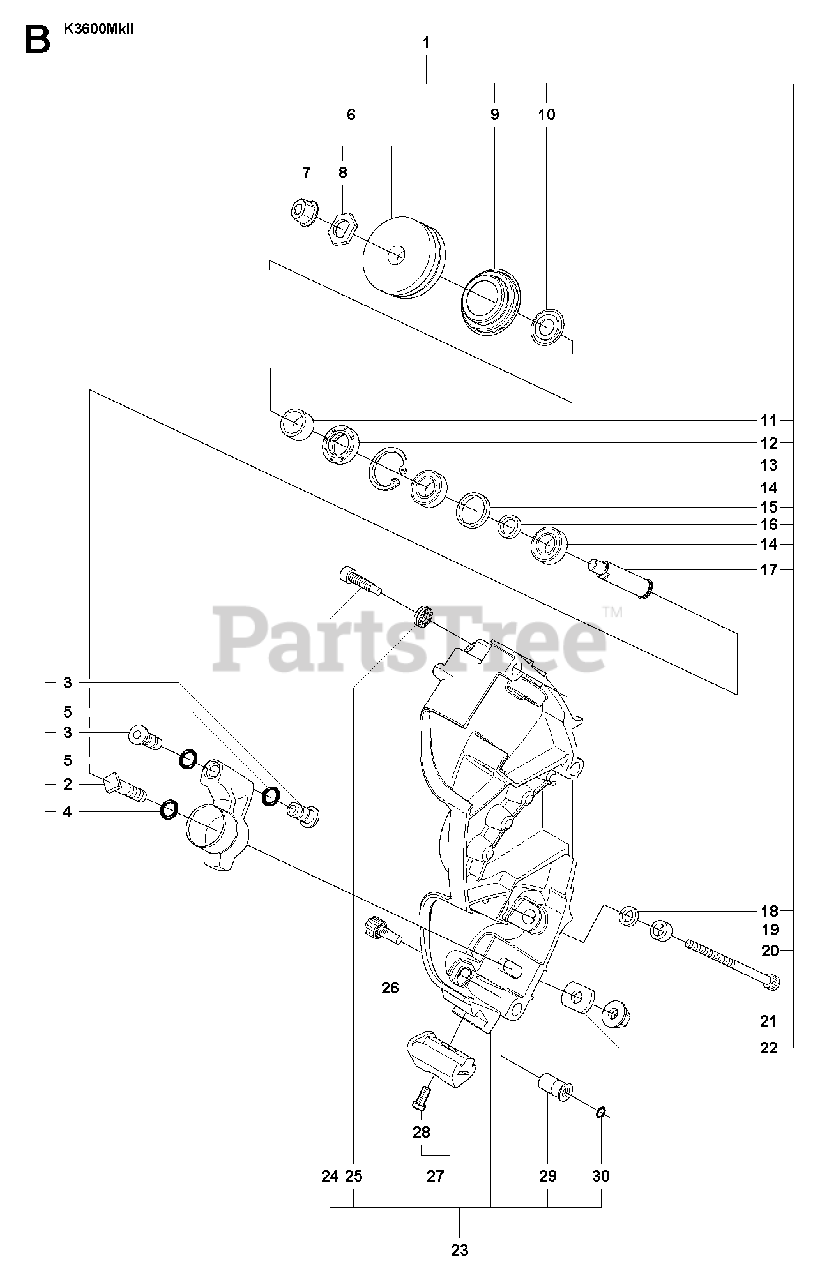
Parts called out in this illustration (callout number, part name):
1	LEVER ASSYIncl. 2 - 6, 9 - 22
6	SUPPORT ROLLERIncl. 7, 8
14	BALL BEARING
20	SCREW ITXSCM
23	COVERIncl. 24 - 25, 29 - 30
27	WEAR PROTECTIONIncl. 28
28	SCREW ITXSCM
